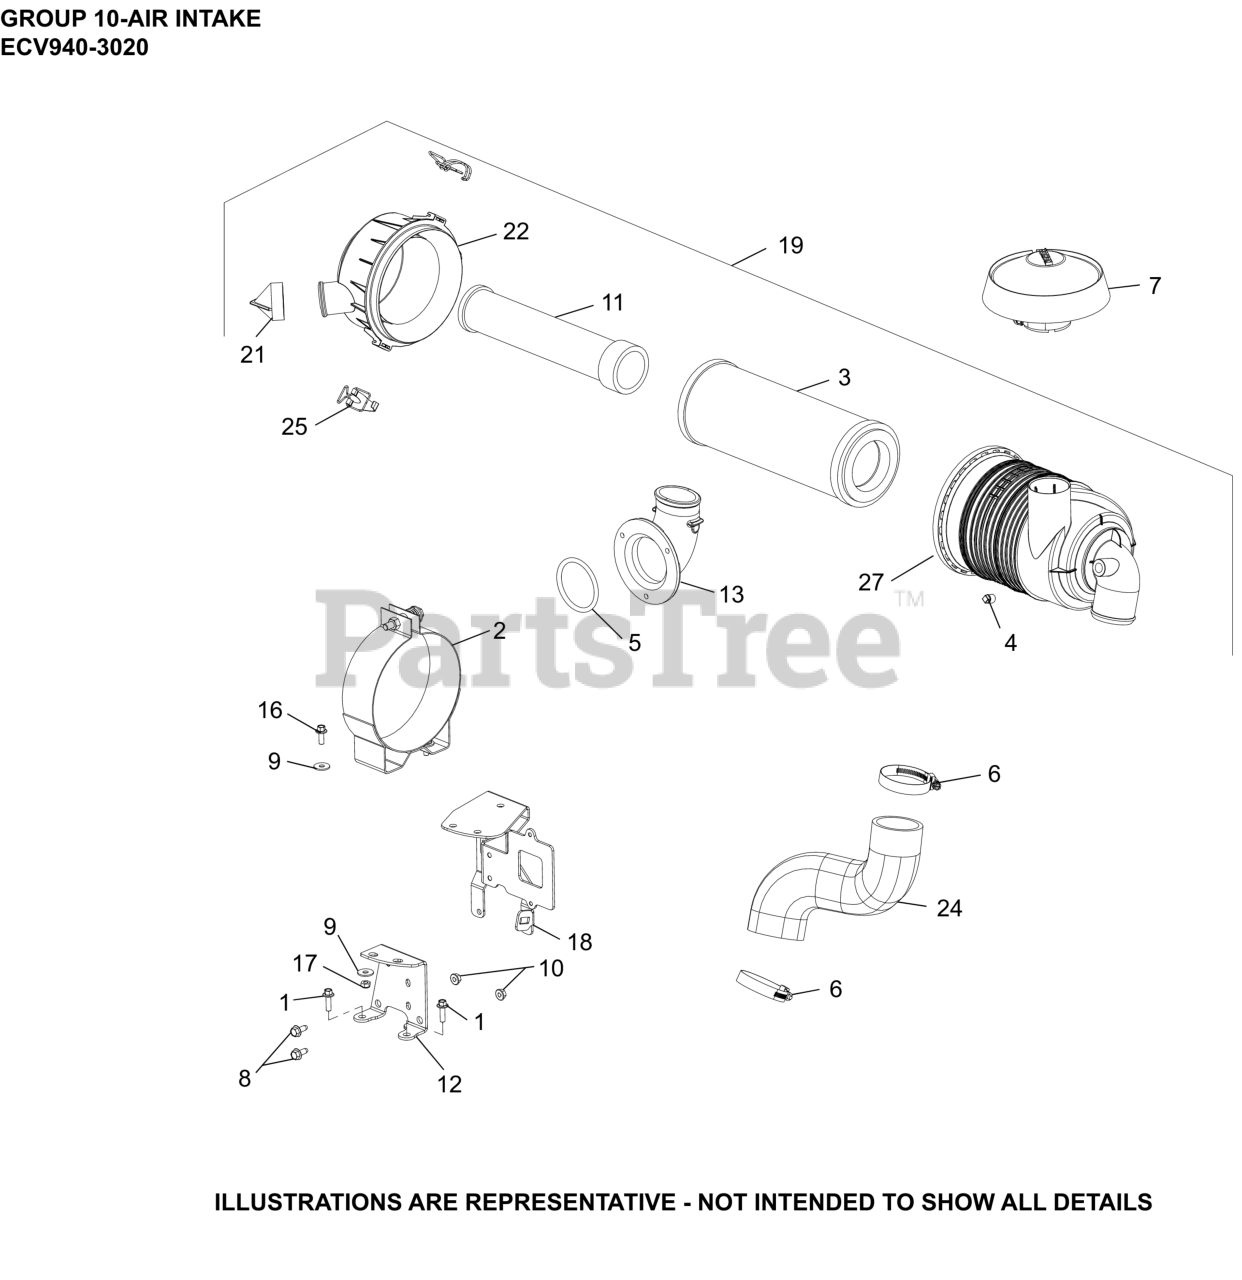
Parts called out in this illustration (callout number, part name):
1	SCREW, FLG M6x1.0x20
2	BRACKET, AIR CLEANER
3	ELEMENT, AIR FILTER - PRIMARY
4	PLUG, PIPE
5	O-RING, AIR CLEANER BASE
6	CLAMP, HOSE
7	HOOD, INLET
8	SCREW, THREAD FORMING
9	WASHER, FLAT 1/4"
10	NUT, FLG M6X1.0
11	ELEMENT, AIR FILTER - SAFETY
12	BRACKET,UPPER REMOTE A/C MOUNTING
13	ELBOW, MACHINING AIR CLEANER
16	SCREW, FLG M6X1.0X16
17	NUT, LOCK M6X1.0
18	BRACKET, LOWER REMOTE A/C MOUNTING
19	AIR CLEANER ASSY-USE 25 048 17-S
21	VALVE, DUST EJECTOR
22	COVER ASSEMBLY, AIR CLEANER
24	HOSE, AIR CLEANER
25	CLIP ASSEMBLY
27	HOUSING, HD AIR CLEANER
NI	MODULE, ECU ECV940
